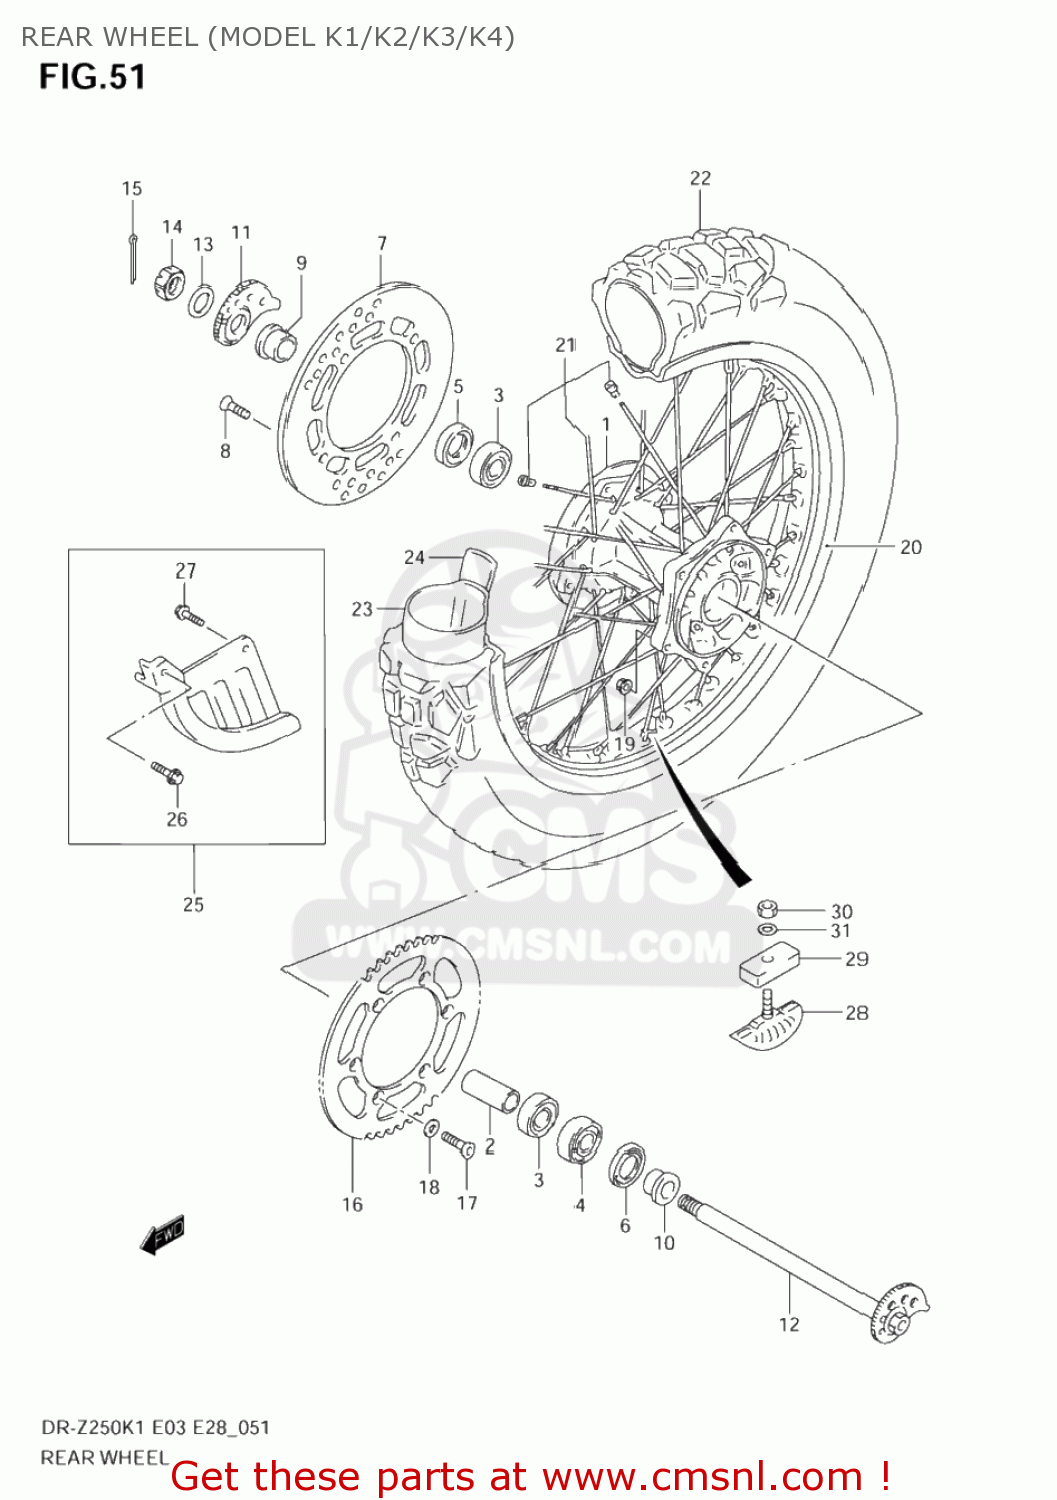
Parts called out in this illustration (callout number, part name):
1	HUB,RR WHEEL
2	SPACER,RR HUB BEARING
3	BALL BEARING
4	BEARING
5	SEAL,OIL(26X42X8)
6	SEAL,OIL(26X47X5)
7	DISC,RR BRAKE
8	BOLT(8X20)
9	SPACER,RR AXLE,R
10	SPACER,RR AXLE,L
11	ADJUSTER,CHAIN,R
12	AXLE,RR
13	WASHER(19X32X3.2)
14	NUT
15	PIN,COTTER
16	SPROCKET,RR(NT:49)
17	SCREW(8X33.5)
18	WASHER
19	NUT
20	RIM,RR WHEEL(18X2.15 AL)
21	SPOKE SET,RR WHEEL
22	TIRE,RR
23	TUBE ASSY,WHEEL INNER
24	PROTECTOR,WHL INR TUBE
25	COVER SET,RR BRAKE DISC
26	BOLT
27	BOLT
28	STOPPER,BEAD(1.85)
29	CUSHION,BEAD STOPPER
30	NUT
31	WASHER
